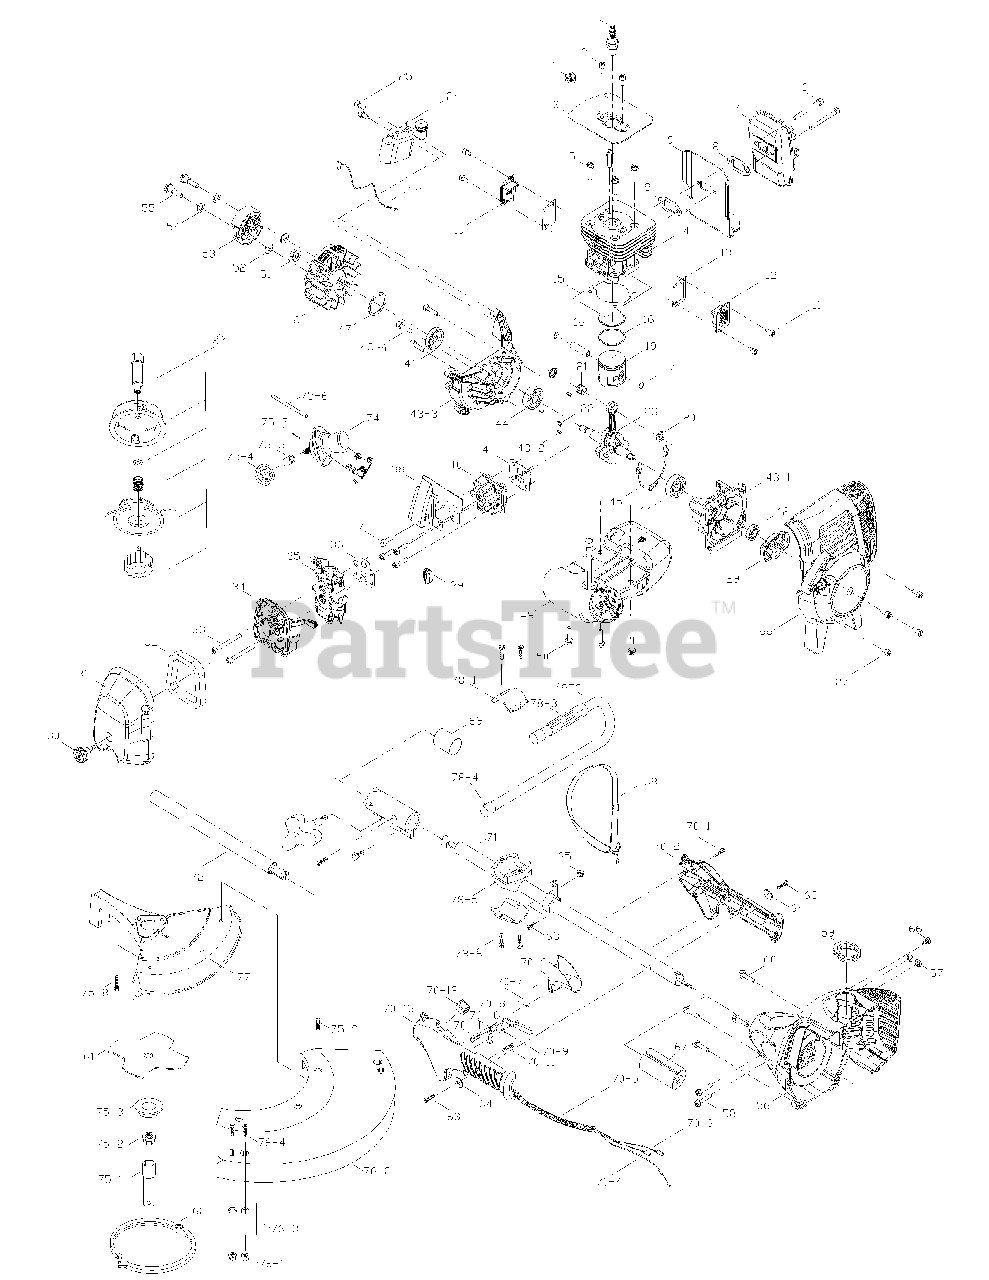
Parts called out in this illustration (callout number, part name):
1	SPARK PLUG
3	PLATE (SPARK SIDE)
7	MUFFLE ASS'Y
8	MUFFLE GASKET
9	MUFFLE PLATE
10	COVER (FLYWHEEL SIDE)
14	CYLINDER
16	PISTON RING
18	PISTON PIN
20	AXLS COVER
21	NEEDLE BEARING
23	CRANK/ROD ASS'Y
24	IGNITION COIL
26	COIL WIRE
28	STARTER HOUSING ASS'Y
29	PAWLS ASS'Y
30	KNOB
31	FILTER COVER
34	FILTER ASS'Y
35	CARBURETOR
36	CARBURETOR GASKET
40	INSULATOR
41	INSULATOR GASKET
43	CRANKCASE ASS'Y
43-1	CRANKCASE (STARTER SIDE)
43-3	CRANKCASE (FLYWHEEL SIDE)
47	C RING
49	FUEL TANK ASS'Y
51	NUT
53	CLUTCH (WITH SPRING)
54	WAVE PLATE
56	TRANSMISSION SUPPORT ASS'Y
61	BLADE, BRUSH 4-TOOTH
62	GUARD, CUTTING BLADE
65	NUT
70	HANDLE ASS'Y
70-2	HOUSING, HANDLE
70-3	WIRE ASS'Y, SWITCH
70-4	THROTTLE CABLE
70-8	LIBERATE SHAFT
70-10	LIBERATE CHUNK
70-13	HOUSING, HANDLE
71	BEHIND HOUSING ASS'Y
72	FRONT HOUSING ASS'Y
73	SRTINGHEAD ASS'Y
74	GEAR HOUSING ASS'Y
75	ACCESSORIES
75-3	FLANGE, SPINDLE
75-5	SPLINE SLEEVE
76	COVER ASS'Y
76-3	KIT, KNIFE
77	SHIELD, BLADE
78	HANDLE ASS'Y
78-5	CENTERPLECE
78-6	PARTS BAG
